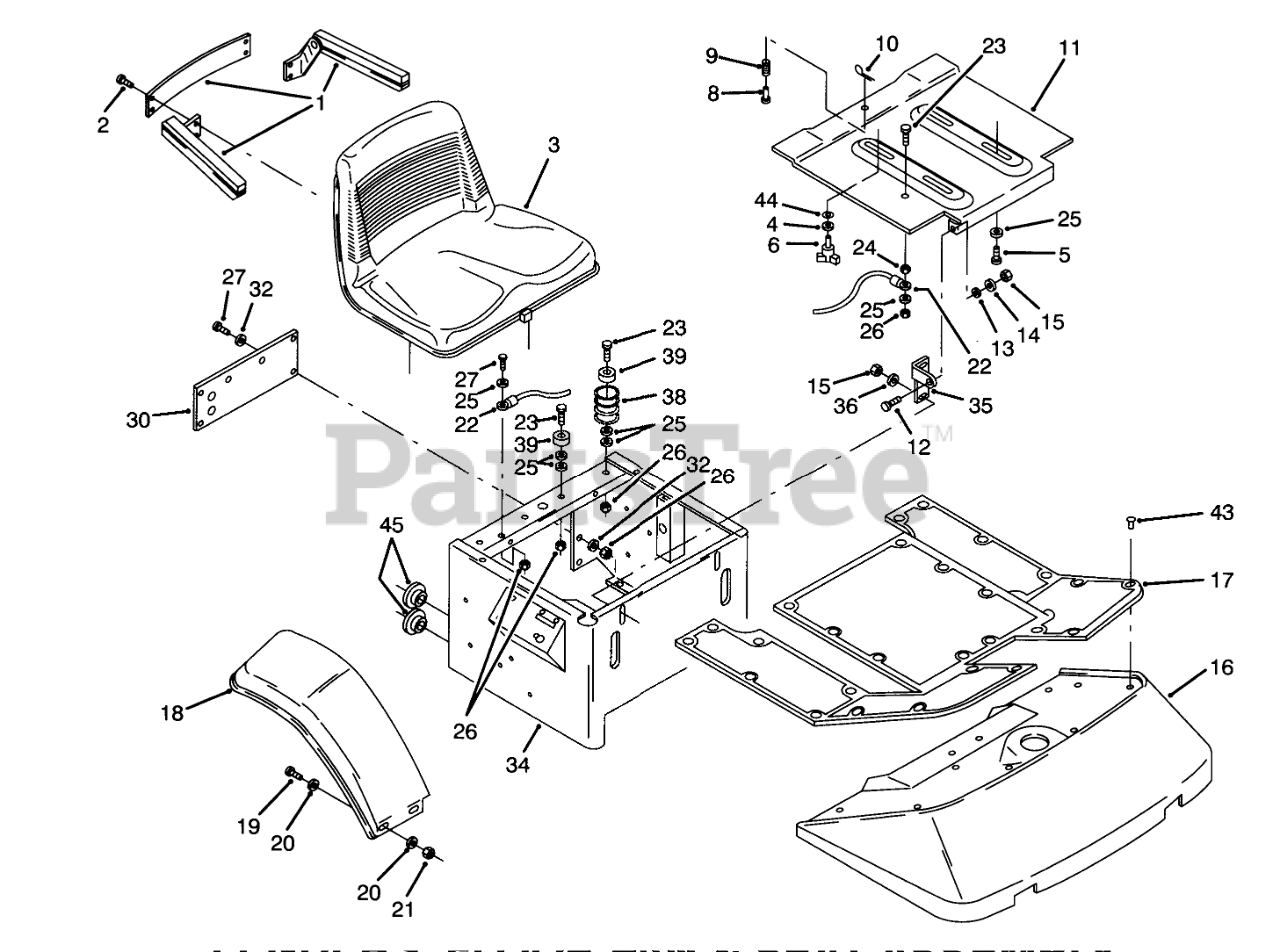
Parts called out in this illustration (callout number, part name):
1	KIT-ARMREST
2	SCREW-HH
3	SEAT V-510
4	WASHER-FLAT
5	BOLT 5/16-18X5/8
9	SPRING-COMPRESSION
10	PIN-COTTER
11	PLATE SEAT PIVOT R
12	BOLT-CARR
13	SPACER
14	WASHER-FLAT
15	NUT-LOCK, NI
16	Floor Pan
17	Black Mat
18	Fender RH
19	SCREW-HH
20	WASHER-FLAT
21	NUT-LOCK, NI
22	Cable
23	SCREW-HH
24	NUT-HEX
25	WASHER-FLAT
26	NUT-LOCK, NI
27	SCREW-HH
30	Cover
32	WASHER-PLAIN
34	SUPPORT-SEAT W A R
35	Seat Pivot Bracket RH
36	WASHER-FLAT
38	SPRING-SEAT NYLON
39	BUMPER
43	RIVET .25 PLASTIC
44	LOCKWASHER INT EXT
45	BUSHING-NYLON 1.500
